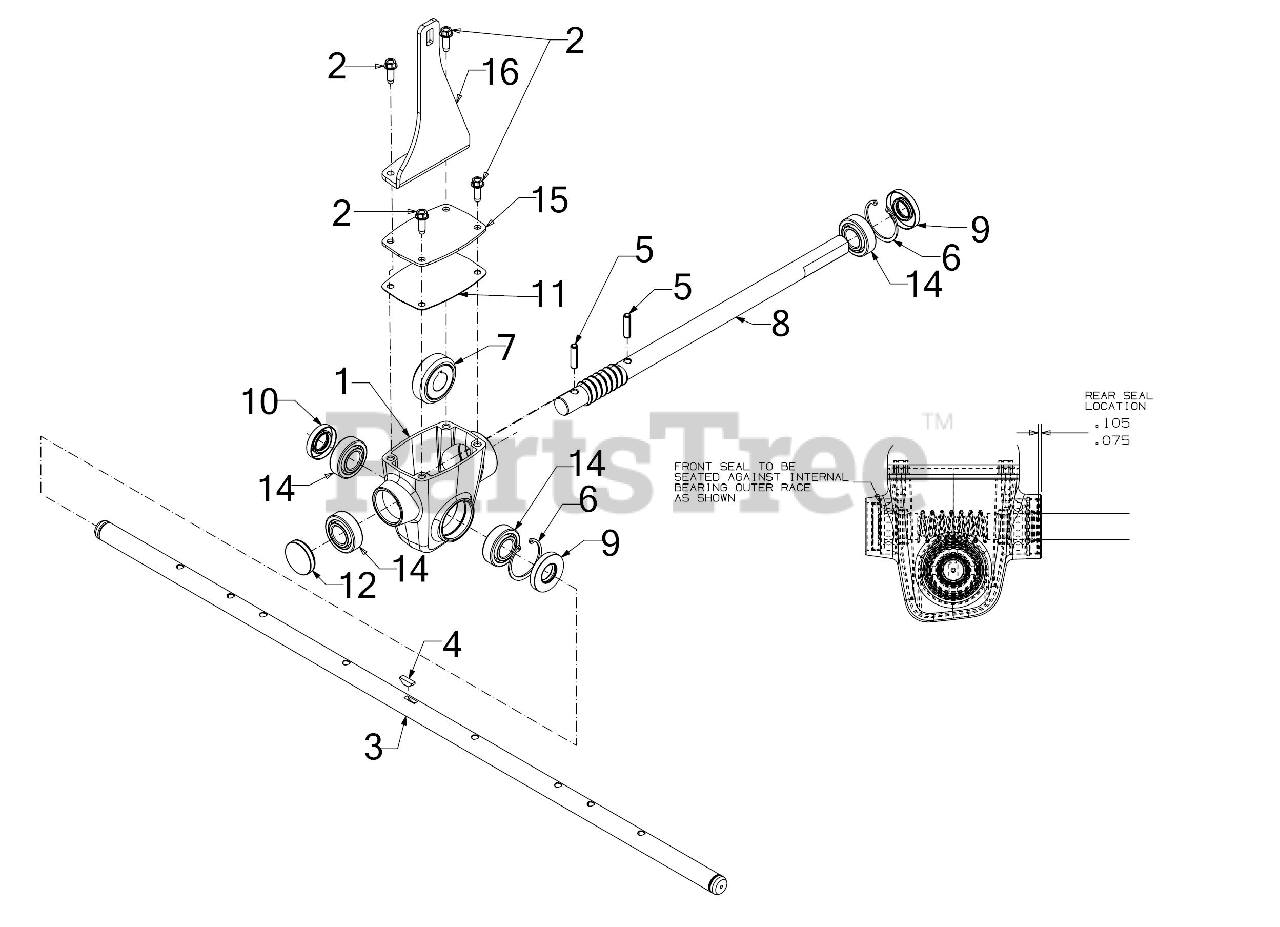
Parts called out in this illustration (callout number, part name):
1	AUGER GEARBOX HOUSING
2	SCREW 1/4-20 x .750
3	34" AUGER AXLE
4	KEY-3/16 x 5/8
5	ROLL PIN
6	SNAP RING
7	WORM GEAR 20T
8	WORM SHAFT .75OD
9	OIL SEAL
10	OIL SEAL
11	GEARBOX COVER GASKET
12	GEARBOX PLUG
14	BALL BEARING
15	GEARBOX COVER
16	GEARBOX SUPPORT BRACKET
